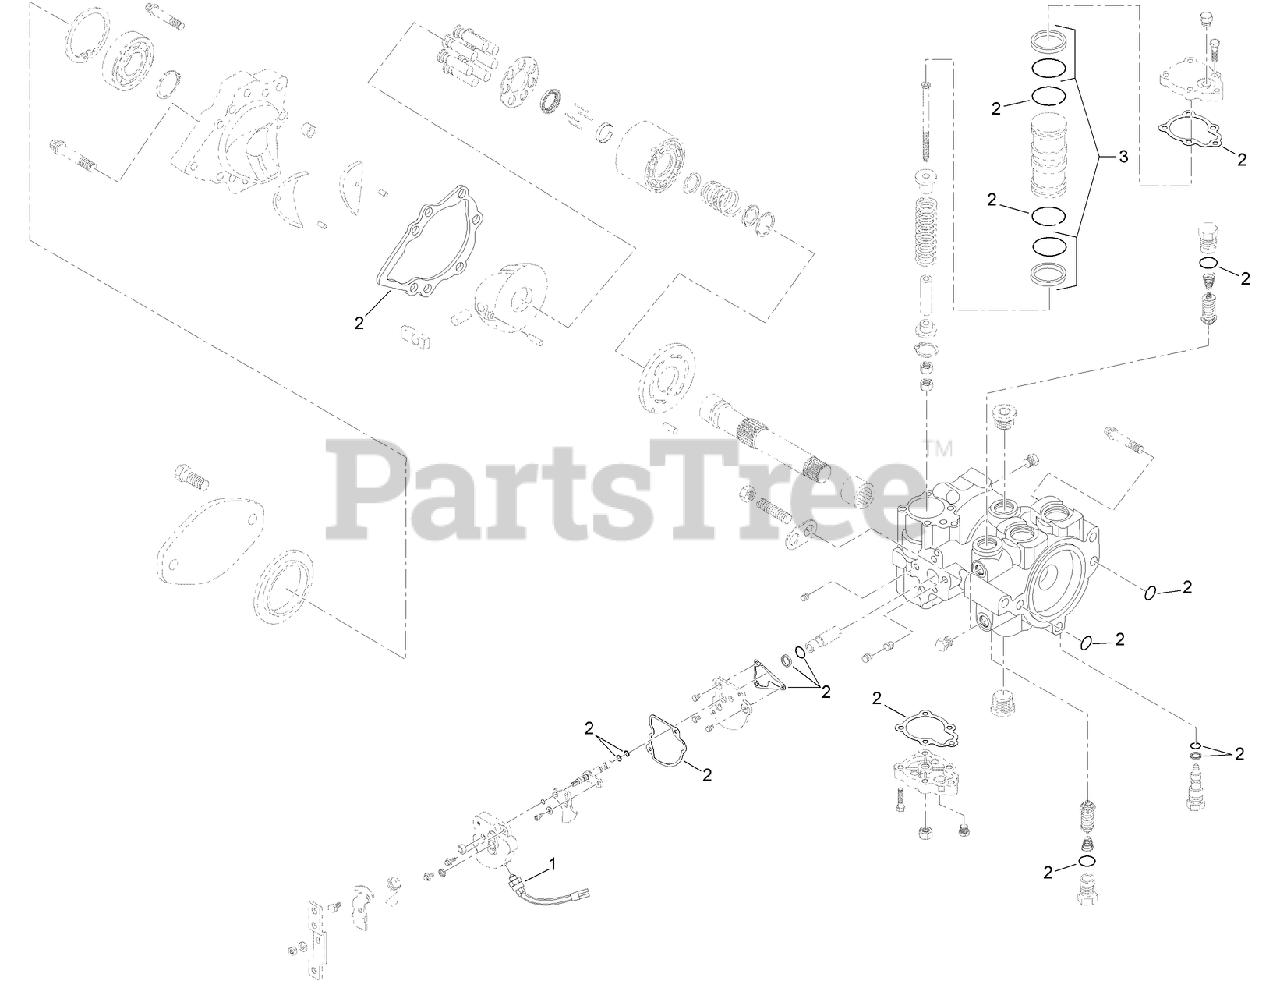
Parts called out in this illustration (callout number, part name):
1	SWITCH-NEUTRAL
2	Overhaul Service Seal Kit - Purchase from Sauer-Danfoss Dealer
3	PISTON RING AND O-RING KIT
